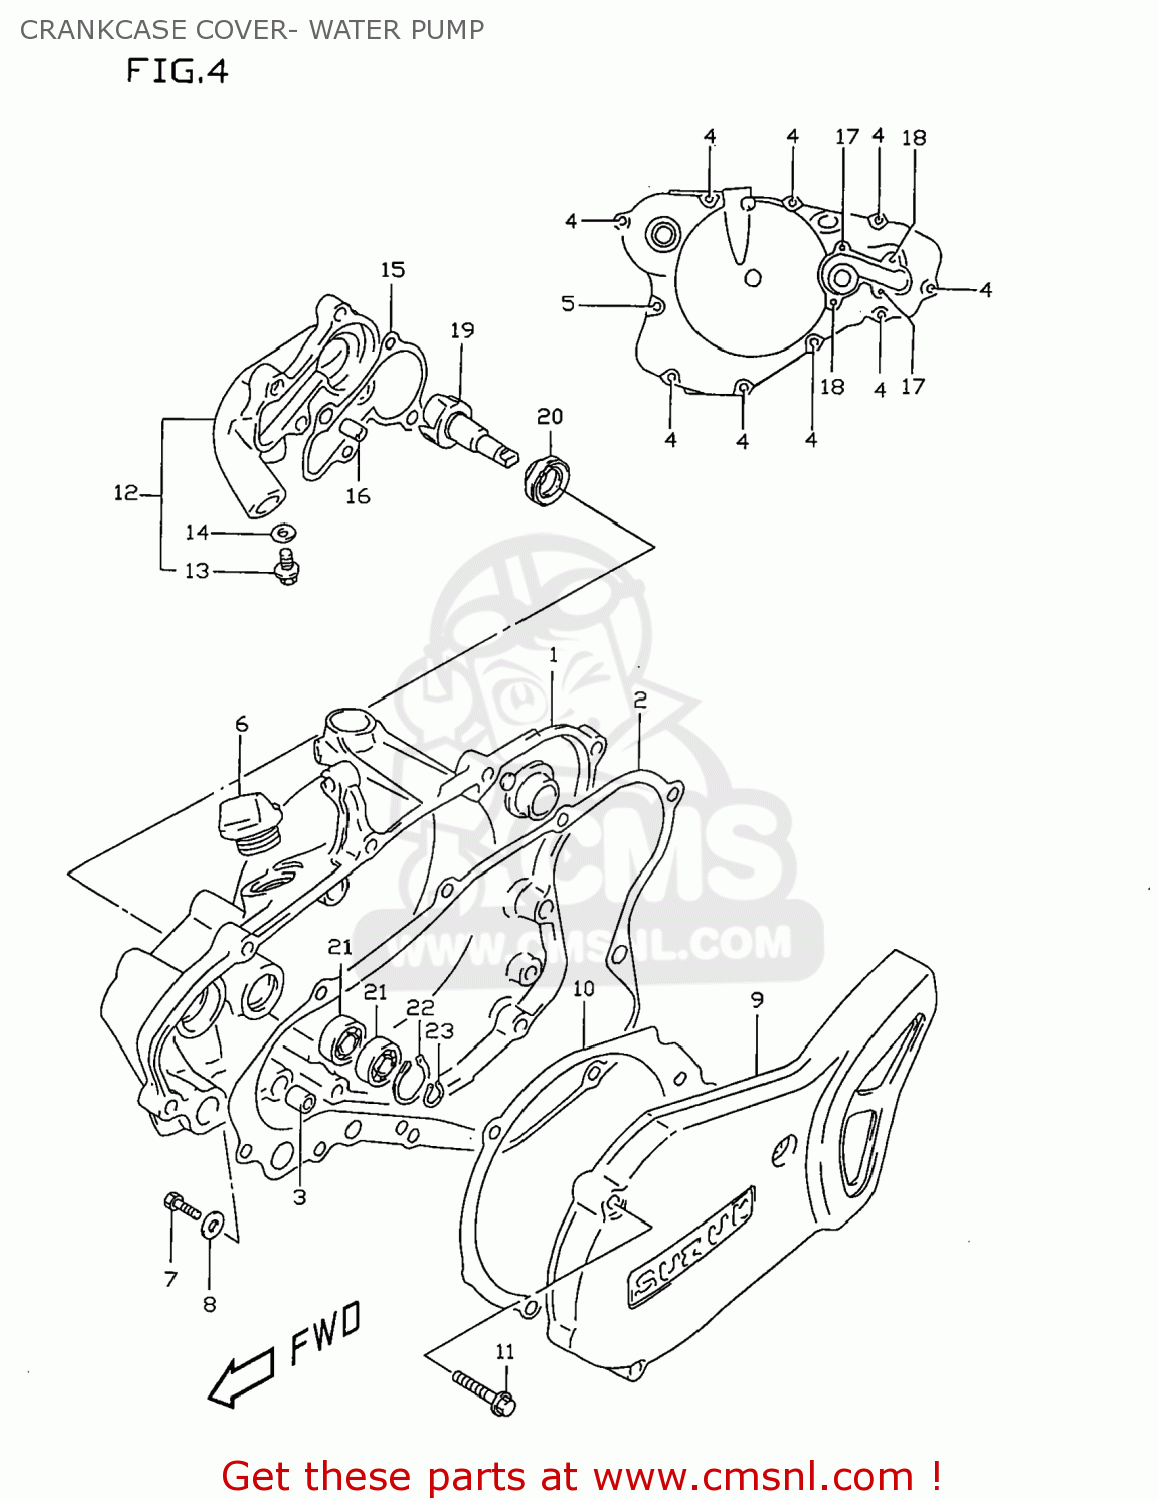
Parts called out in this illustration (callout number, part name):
1	COVER,CLUTCH
2	GASKET,CLUTCH COVER (NAS)
3	PIN
4	SCREW
5	BOLT
6	PLUG SET
7	SCREW(6X10)
8	GASKET(6.2X11X1).2 (NAS)
9	COVER,MAGNETO
10	GASKET,MAGNETO COVER (NAS)
11	SCREW
12	CASE,WATER PUMP
13	BOLT
14	WASHER
15	GASKET,WATER PUMP CASE (NAS)
16	PIN
17	SCREW
18	BOLT,G/S SWITC
19	IMPELLER,WATER PUMP
20	SEAL,WATER PUMP OIL
21	BEARING
22	CIRCLIP
23	CIRCLIP
